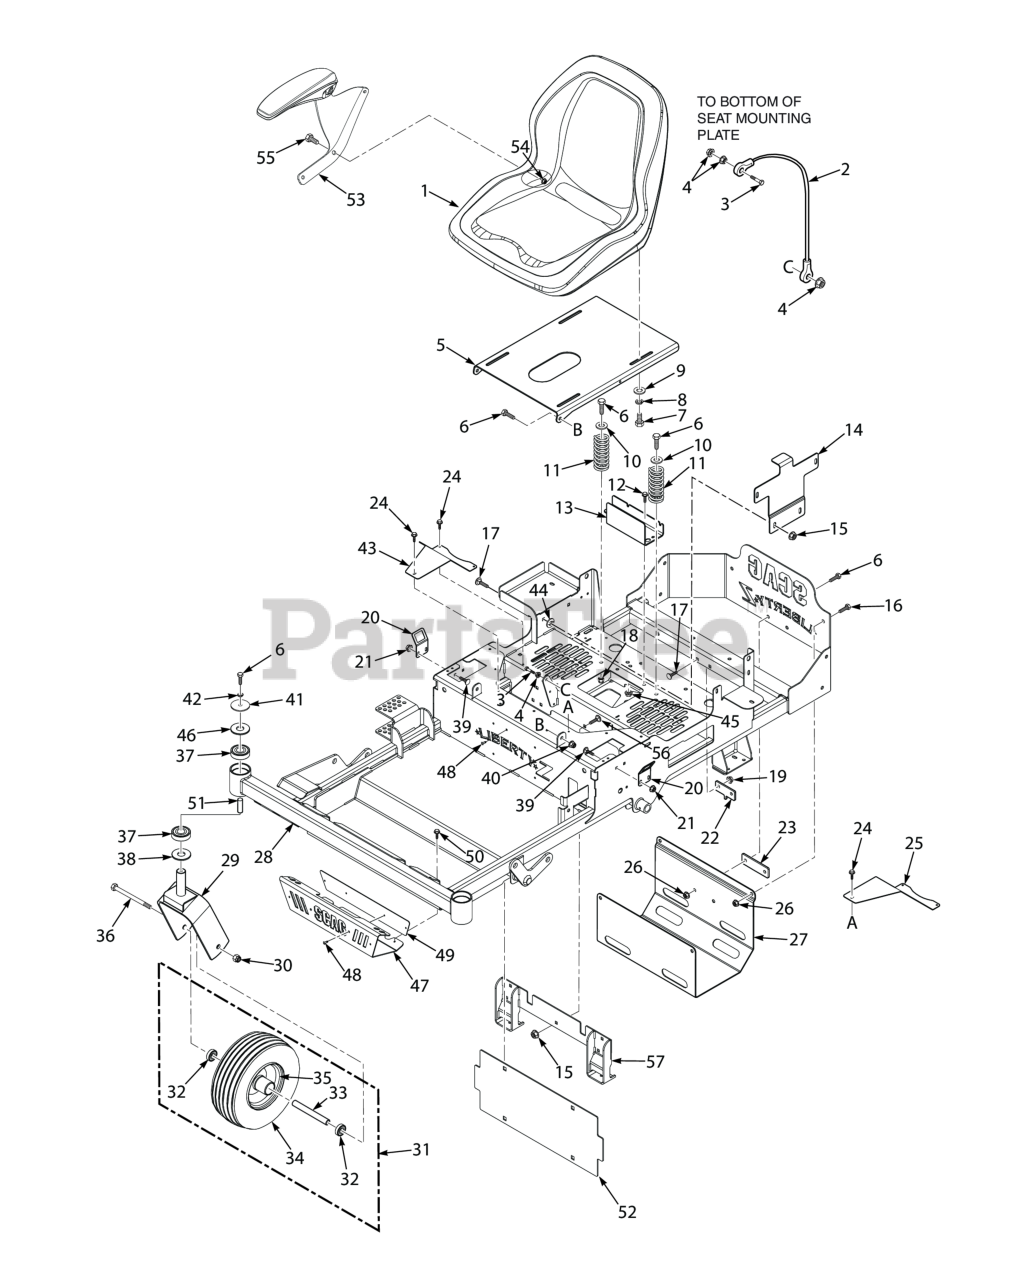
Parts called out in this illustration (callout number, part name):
1	Seat, SZL w/Armrests
2	Cable, Seat Stop
3	SERR. FLG. HEX HEAD CAPSCREW, 5/16-18 X 3/4
4	NUT, 1/4-20 SERRATED FLANGE HEX HEAD
5	Seat-Plate W/Decal
6	Bolt, Hex Head, 3/8-16 x 1 Gr. 5
7	Bolt, Heax Head 5/16-18 x 1" (48V / 52V)
8	Lockwasher, 5/16 (.317 x .586 x .078) Helical Spring
9	Flatwasher, 5/16-.375 x .875 x .083 (35BV & 37BV-EFI)
10	Flatwasher, 3/8" Special (.391 x .938 x .105)
11	Spring, Seat
12	Capscrew, 5/16-18 x .75 Serrated Flange Hex Head
13	Channel, Hose
14	Battery Hold Down
15	Nut, Flange Head Elastic Stop 5/16-18
16	Bolt, Hex Head, 3/8-16 x 3/4"
17	Bolt, 5/16-18 x .75 RHSN Carriage
18	HEX NUT, ELASTIC STOP LOCK, 3/8-16
19	Nut, Flange Head Elastic Stop 5/16-18
20	Bracket, Switch
21	Nut, Flanged Elastic Stop 1/4-20
22	Plate, Anti-Rotation
23	Plate, Spacer
24	Screw, #10-32 x .563 Shakeproof
25	Guard, Belt - LH
26	NUT, 3/8-16 SERRATED FLANGE HEX HEAD
27	Skid Plate, SZL
28	Mainframe w/Decals - SZL61H
29	Caster Assembly
30	HEX LOCKNUT, ELASTIC STOP, 1/2-13
31	CASTER WHEEL ASSY, 11.00 X 6.00-5
32	Bearing
33	SPACER, WHEEL BEARING
34	TIRE, 11 X 6.00-5
35	RIM ASSY, 5 X 3 W/5.625 LG HUB
36	Bolt, Hex Head 1/2-13 x 7-1/2" (48"/52")
37	Bearing
38	Spacer, Yoke
39	Serr. Fl. Hex Head CPSCR, 1/4-20 x 3/4"
40	Nut, Flange Elastic Stop Nut, 3/8-16
41	Flatwasher, 3/8-.406 x 2.25" x .1875
42	Lockwasher, 3/8" Spring, Kawasaki FX / FT & FT-EFI / B&S 32BV
43	GUARD, BELTS - RH
44	Nut, Push-On 5/16-18
45	Nut, Serrated Flange 5/16-18 (Right Front Engine Mounting, Briggs and Kohler Only)
46	Flatwasher, 7/16" (.500 x 1.25 x .083")
47	Bumper. Front
48	Rivot, 3/16 x .402 POP
49	Plate, Decal
50	Screw, 1/4-20 x .375"
51	Spacer, Caster Bearing
52	Plate, Backing
53	Armrest, RH (48H, 52H, 61H)
54	SPEED U-NUT,1/4-14
55	SCR,HHSCR, 1/4-14 X1 TYPA THRD FRMNG
56	Bolt, 5/16-18 x .75 RHSN Carriage
57	Mounting Weldment, Axle - Tuff Torq
